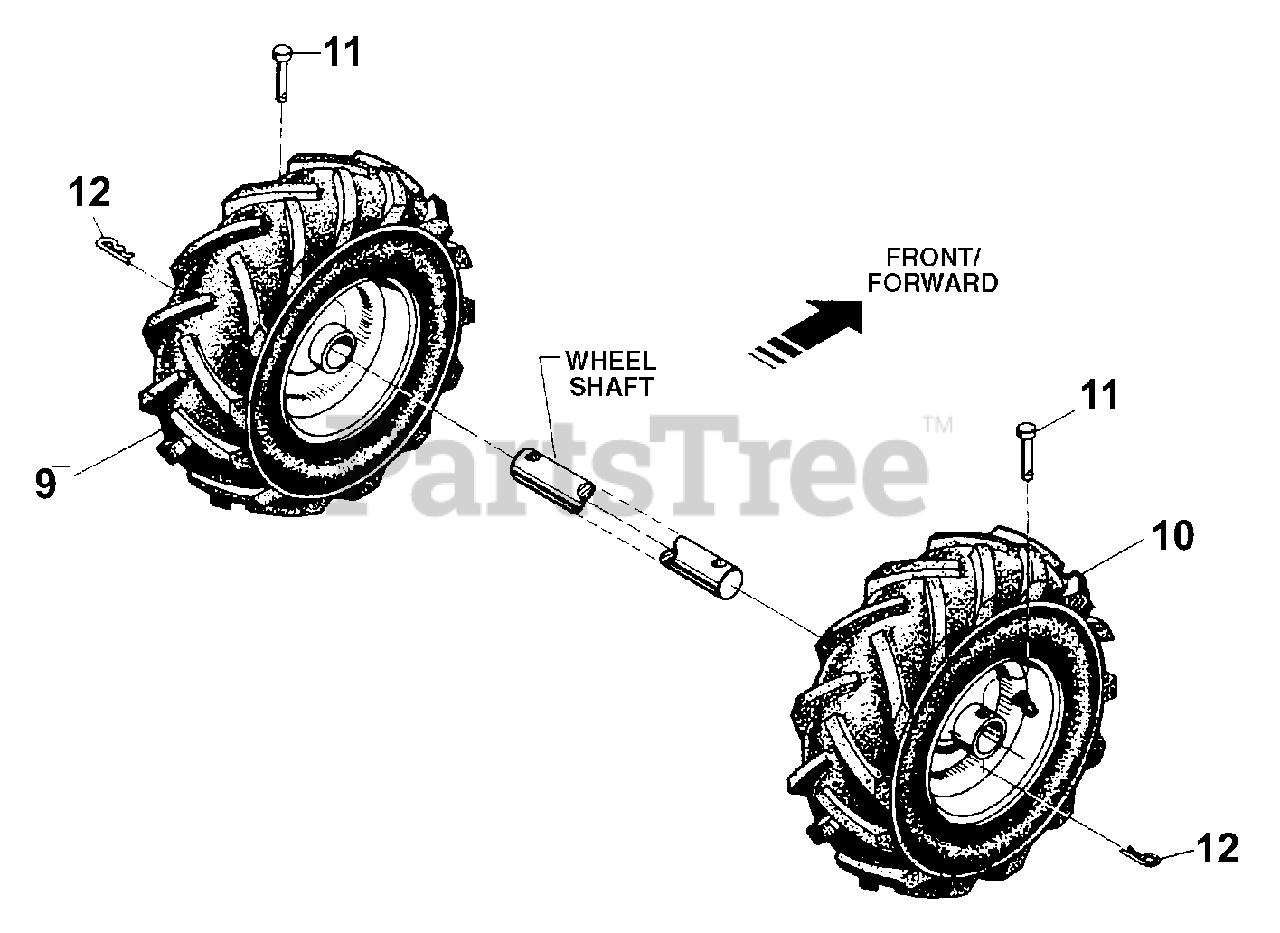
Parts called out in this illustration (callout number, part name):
9	Wheel & Tire Assy., left-side
10	Wheel & Tire Assy., right-side
11	Clevis Pin, .312 x 1-3/4 long
12	Hitch Pin
